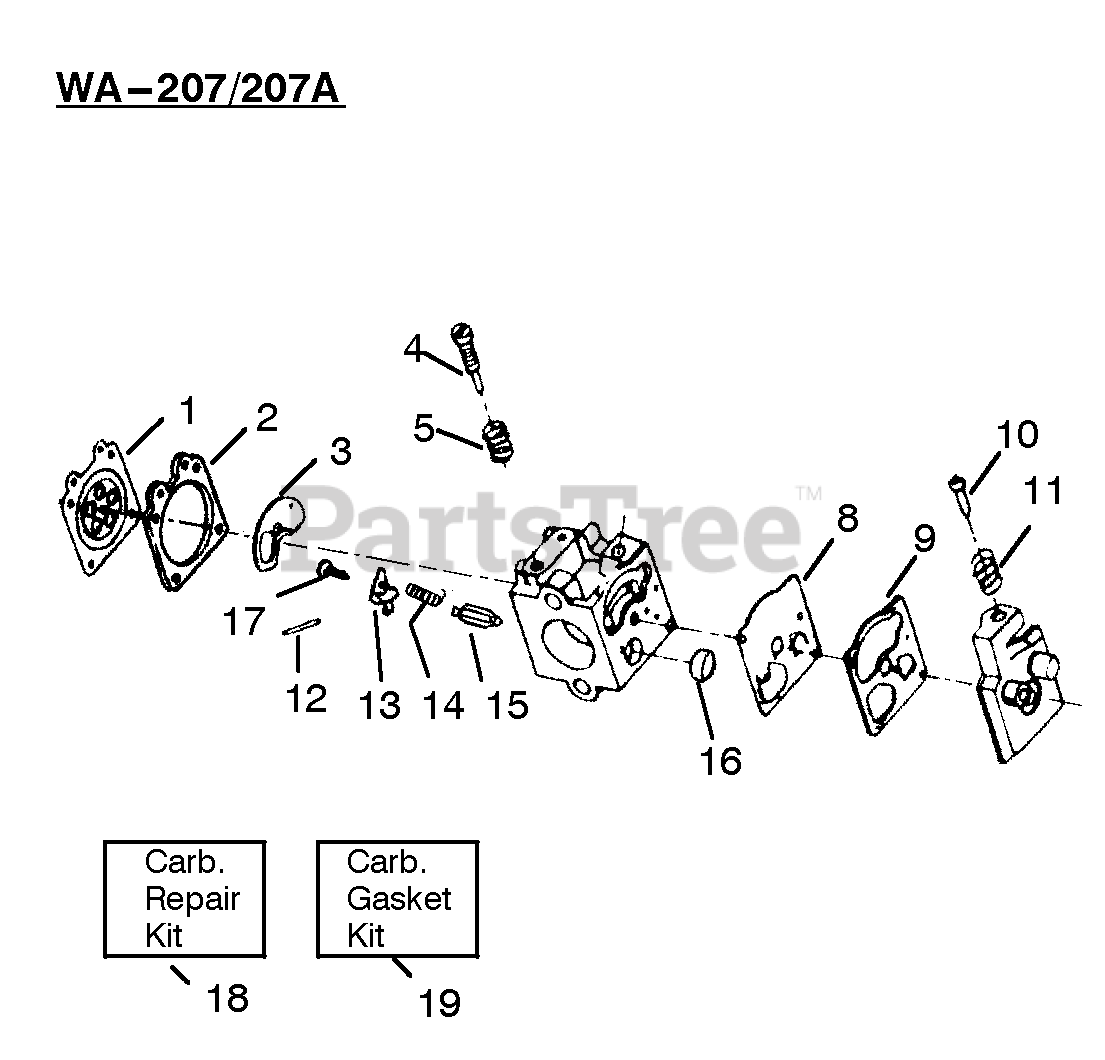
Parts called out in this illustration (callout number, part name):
1	Metering Diaphram
2	Metering Diaphragm Gasket
3	Circuit Plate Gasket
4	Mixture Needle
5	Mixture Needle Spring
8	Fuel Pump Diaphragm
9	Fuel Pump Gasket
10	Idle Speed Screw
11	Idle Speed Spring
12	Metering Lever Pin
13	Metering Lever
14	Metering Lever Spring
15	Inlet Needle Valve
16	Fuel Inlet Screen
17	Metering Lever Pin Screw
18	Carb. Kwik Repair Kit
19	Carb. Gasket/Diaphragm
